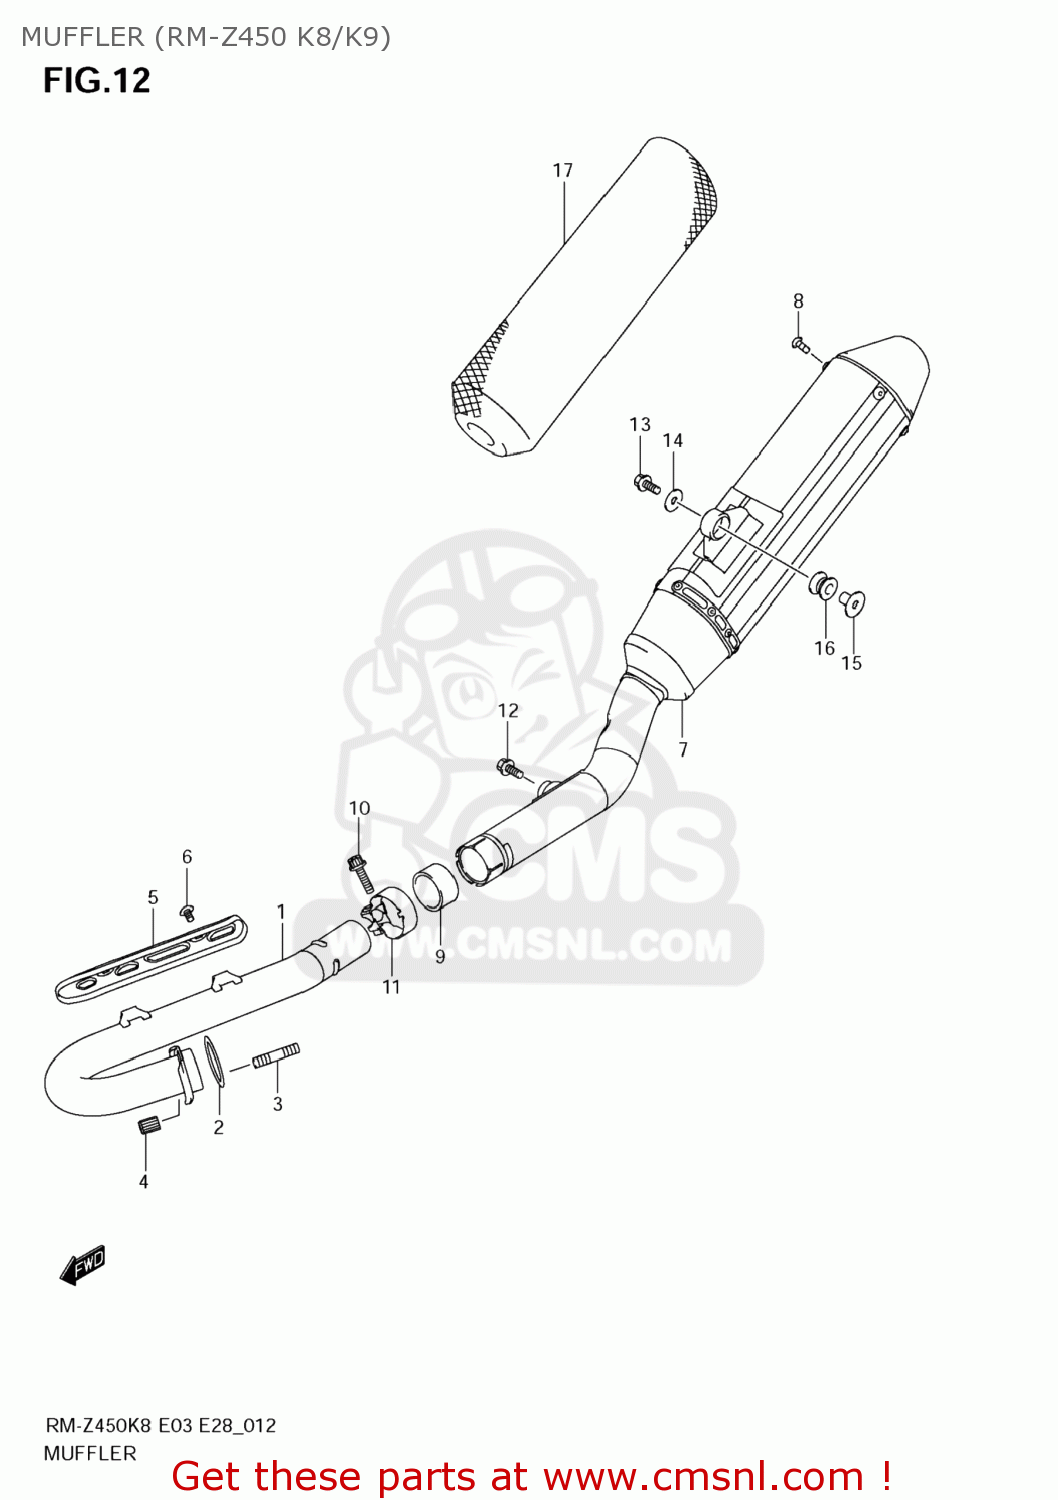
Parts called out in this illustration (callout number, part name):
1	PIPE,EXHAUST
2	GASKET,EXHAUST PIPE (NAS)
3	BOLT,STUD
4	NUT
5	COVER,EXHAUST PIPE
6	SCREW(6X10)
7	BODY,MUFFLER
8	SCREW(5X13)
9	CONNECTOR,MUFFLER
10	BOLT
11	CLAMP,CONNECTOR
12	BOLT(8X20)
13	BOLT(8X35)
14	WASHER(8.5X26X1.6)
15	SPACER(8.6X12X17.5)
16	CUSHION
17	SILENCER,MUFFLER
